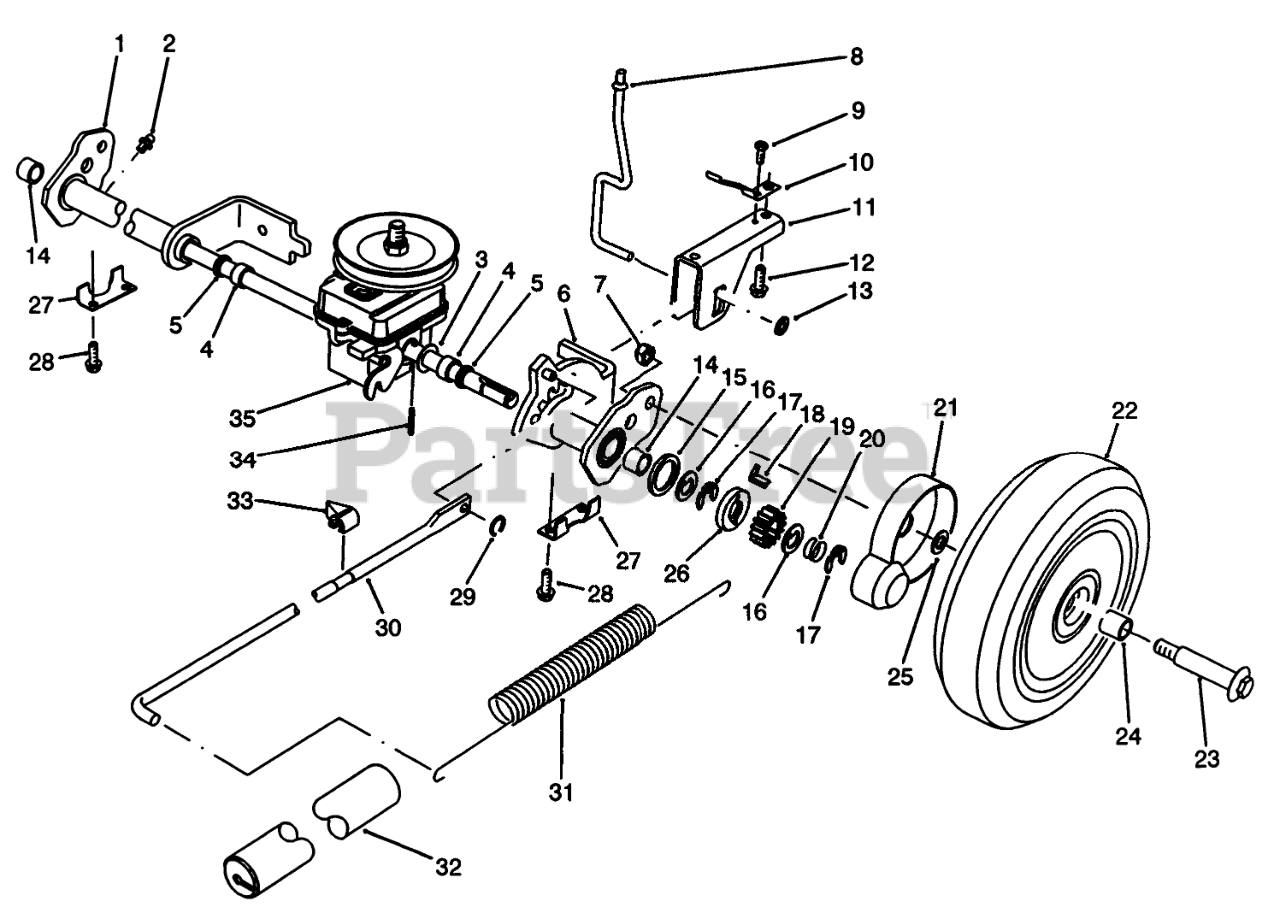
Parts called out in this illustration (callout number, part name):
1	Rear Pivot Assembly R.H. (Incl. Ref. #2, 4, 5 & 14)
2	FITTING-GREASE
3	WASHER-PLAIN
4	BUSHING
5	SEAL-OIL
6	Rear Pivot Assembly L.H. (Incl. Ref. #2, 4, 5 & 14)
7	NUT-HEX
8	TRIGGER ROD
9	SCREW 8 - 32 X 250
10	SPRING - TRIGGER RET
11	SADDLE - HOC
12	SCREW
13	PUSHNUT
14	BEARING-ROLLER
15	RING-FRICTION
16	WASHER-THRUST, KEYED
17	RING-CLIP, LOCKING
18	KEY-ROCKING, LH
19	GEAR-PINION
20	SPRING-COMPRESSION
21	COVER-WHEEL
22	Wheel, Tire & Gear Assy. (Incl. Ref. #24)
23	BOLT-WHEEL
24	BUSHING
25	SPACER-COVER, WHEEL
26	WASHER-CLUTCH
27	REAR SECURING PLATE
28	SCREW-HWH
29	GRIP RING
30	LINK ROD
31	SPRING-COUNTERBALANCE
32	COVER-SPRING
33	INDICATOR-HEIGHT OF CUT
34	COIL PIN
35	Gearbox Assembly
